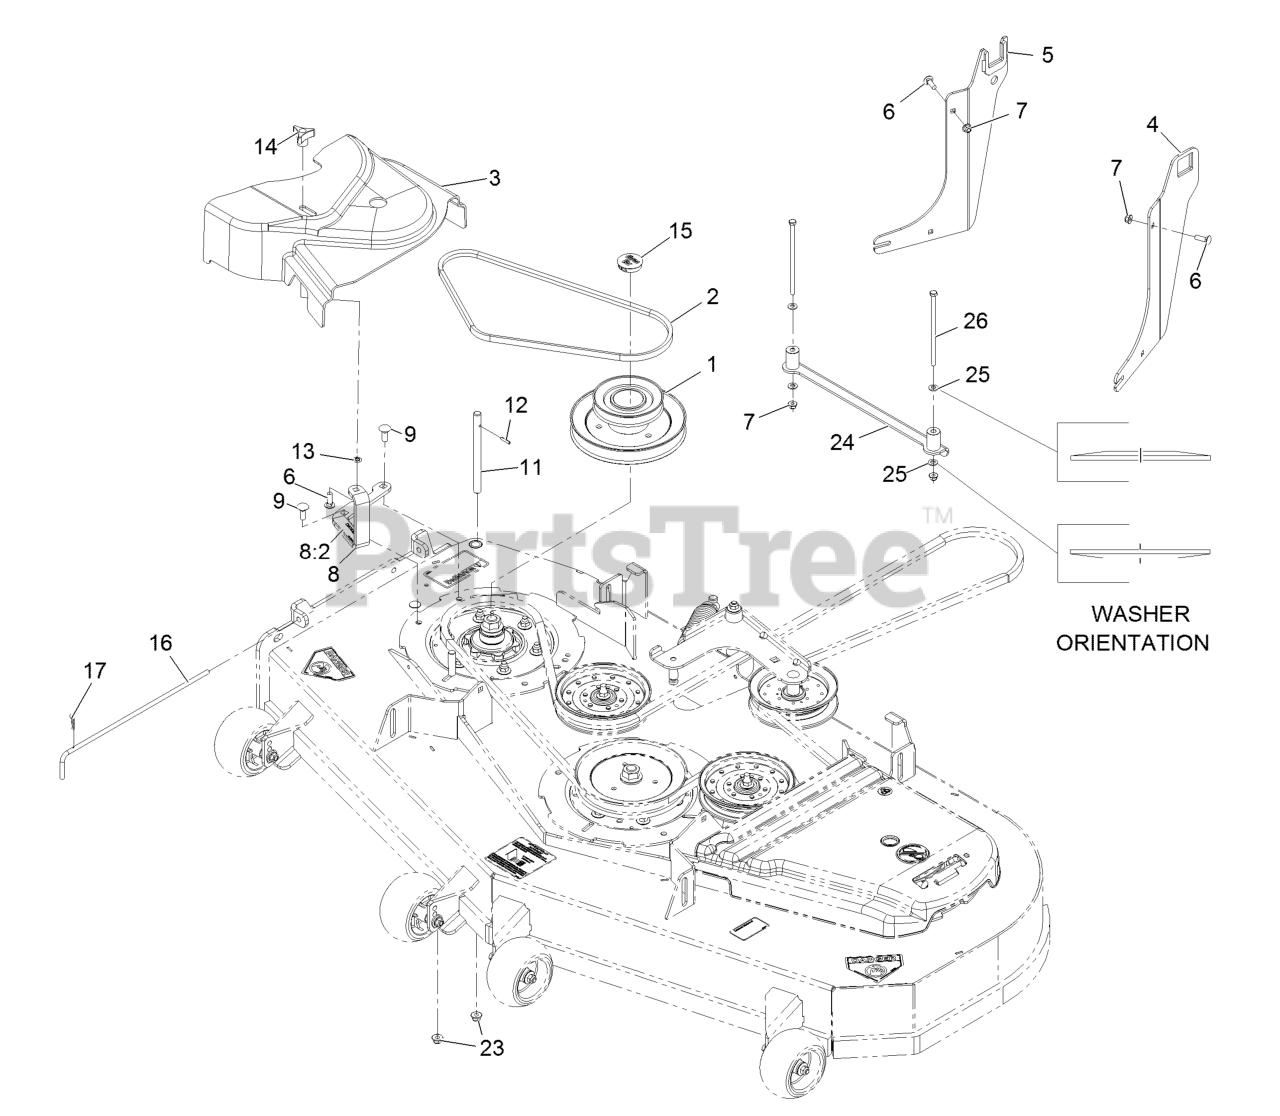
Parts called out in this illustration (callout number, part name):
1	JACKSHAFT,UV DRIVE 604 SPLINED
2	BELT,A 42.32
3	COVER-BELT UVE 60
4	BRACKET ASM, LH
5	BRACKET ASM, RH
6	BOLT-CARR
7	NUT-HF, NI
8	ASM-CVR BRKT W/DECAL
8:2	DECAL-COVER, MISSING
9	BOLT-CARR
11	SHAFT-CATCHER, GRASS
12	PIN-ROLL
13	RING-RETAINING, BOLT
14	KNOB-3 PRONG
15	PLUG, BLACK NYLON 1.75
16	PIN,CHUTE PIVOT
17	PIN-COTTER
23	Nut-Nyloc 3/8-16 Flg
24	ASM-HYDRO GUSSET
25	WASHER-SPRING
26	SCREW HH
